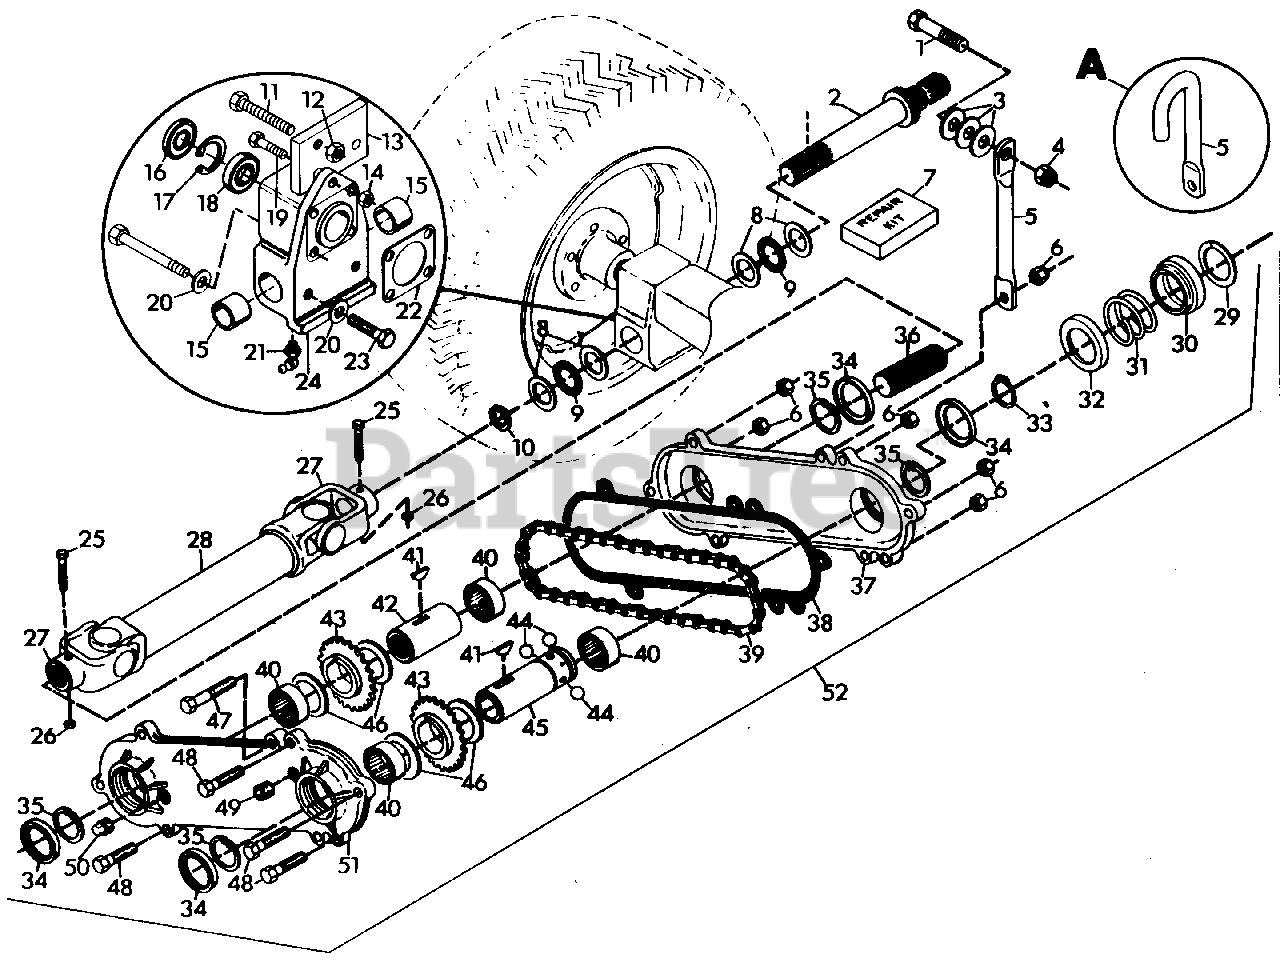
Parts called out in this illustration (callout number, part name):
1	Bolt, Hex 1/2-13x2.00
2	Shaft
3	Washer, Flat .500x1.250x.083
4	Nut, Lock 1/2-13
5	Bracket, Rear PTO
6	Nut, Lock 3/8-16
7	Kit, Repair U-Joint
8	Race, Bearing Thrust
9	Bearing, Needle Thrust
10	Ring, Retaining 1.00 Shaft
11	Bolt, Hex 3/8-16x2.50
12	Nut, Jam 3/8-16 Hex
13	Plate, Fwd Clutch Anchor
14	Nut, Lock 5/16-18
15	Bearing, Bronze 1.002x1.378x1.00
16	Seal, Oil Axle
17	Ring, Retaining
18	Bearing, Ball 1.250x2.250x.500
19	Bolt, Hex 5/16-18x1.25
20	Washer, Lock 1/2 Reg.
21	Fitting, Lube 90 Degree
22	Gasket
23	Bolt, Hex 1/2-13x1.25
24	Assembly, Axle Retainer
25	Bolt, Hex 1/4-20x2.00
26	Nut, Lock 1/4-20
28	Shaft, Drive(Rear)
29	Ring, Snap
30	Collar
31	Spring
32	Retainer, Inner
33	Ring, Retaining
34	Seal, Oil 1.500x2.125x.312
35	Ring, Retaining
36	Shaft
37	Housing, Rear
38	Gasket
39	Chain, Roller
40	Bearing, Needle 1.500x1.875x.50
41	Key, Woodruff .187x.625 Hard #61
42	Shaft
43	Sprocket, 5/8 Pitch 14 Teeth
44	Ball, 3/8
45	Shaft
46	Bearing, Thrust Race
47	Bolt, Hex 3/8-16x2.50
48	Bolt, Hex 3/8-16x2.00
49	Plug, Vented
50	Plug, Pipe .50 Sq Hd Steel
51	Housing, Front
52	Assembly, Drive Chain
